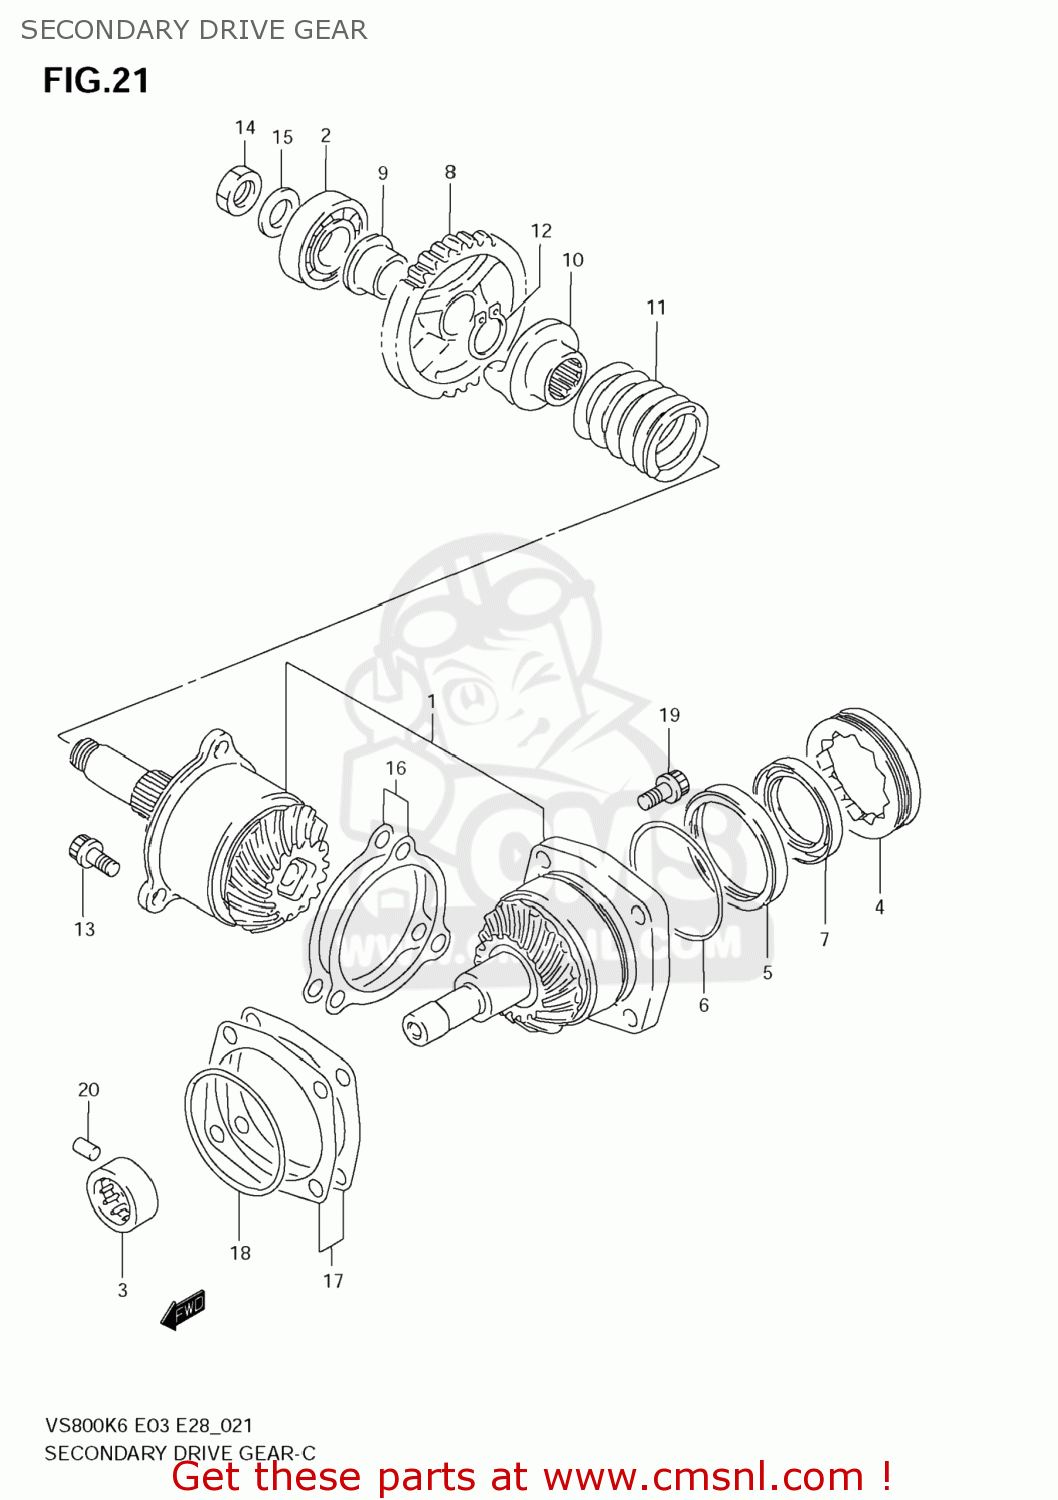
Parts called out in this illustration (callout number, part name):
1	GEAR & HOUSING SET,SECONDARY
2	BEARING(20X52X15)
3	BEARING(20X34X16)
4	STOPPER,SEC DRIVEN BEARING
5	HOUSING,OIL SEAL
6	O RING(D:1.2,ID:59.6)
7	SEAL,OIL(38X54X8.5)
8	GEAR,REDUCTION DRIVEN(NT:30)
9	BUSH,REDUCTION DRIVEN GEAR
10	DOG,OUTPUT CAM
11	SPRING
12	CIRCLIP
13	BOLT
14	NUT
15	WASHER(16X29X4)
16	SHIM SET,SEC DRIVE GEAR
17	SHIM SET,SEC DRIVEN HOUSING
18	O RING(D:2.1,ID:66.2)
19	BOLT
20	PIN
